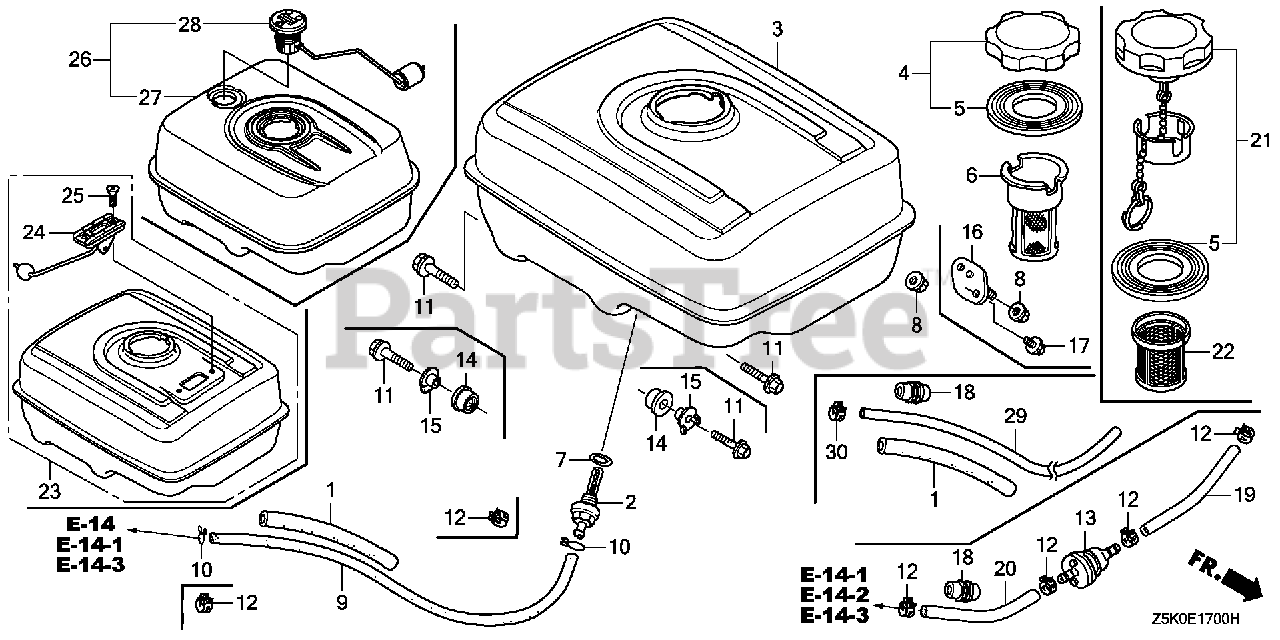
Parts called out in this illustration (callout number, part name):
1	RUBBER, SUPPORTER (107MM)
9	TUBE, FUEL (4.2X210) (FKM)
9	TUBE, FUEL (4.5X210) (FKM)
12	CLAMP, TUBE (D8)
